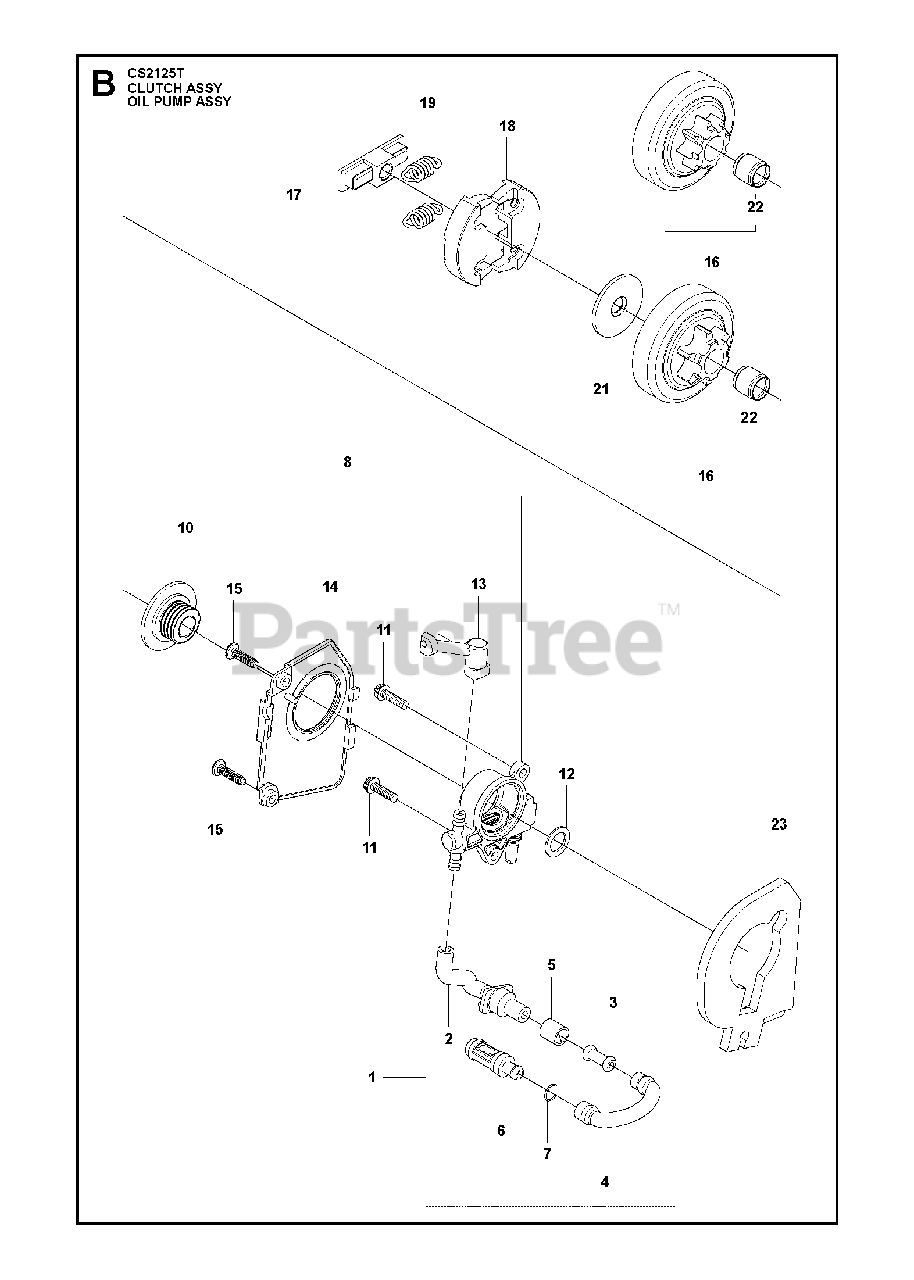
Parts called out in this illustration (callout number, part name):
6	FILTER
7	RING
8	RP OIL PUMP ASSY
10	OIL PUMP (WORM 199-18)
22	BEARING
